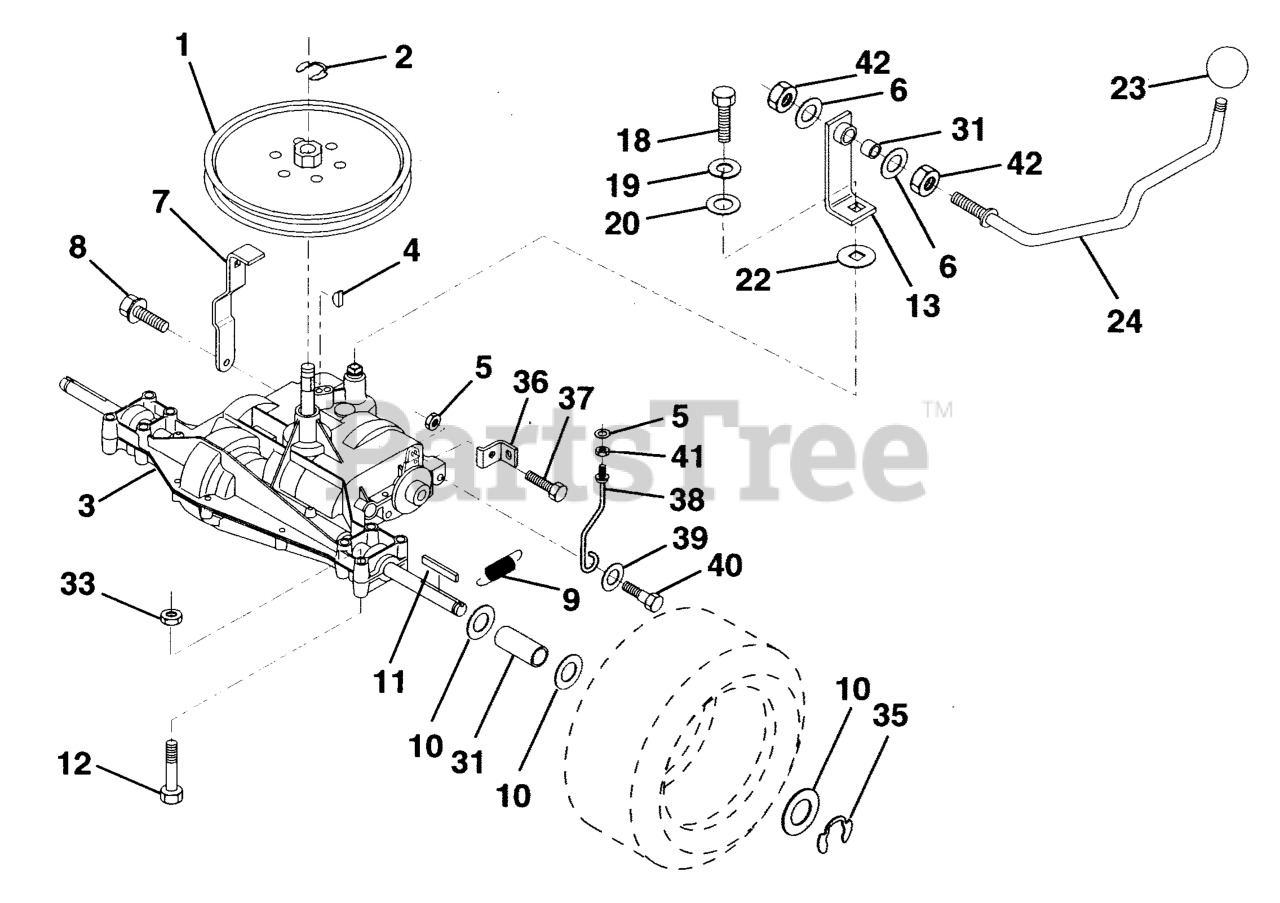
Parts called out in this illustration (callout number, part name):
2	RETAINING RING LT
4	KEY STD (1373) DANA
5	LOCKNUT
7	STRAP TORQUE
8	SCREW.THDROL.5/16-18X3/4.TTY
9	SPRING T
11	SQUARE KEY
12	Bolt Fin Hex 3/8 - 16 x 2 3/4
13	BRACKET NLA
18	Bolt, Hex Head, Fin. l/4-28 UNF x 3/4 Grade 8
19	LOCKWASHER
20	WASHER LT
22	WASH-SHFT PLT LT
23	KNOB T (1/2-HOLE)
36	Bracket Brake
37	RP BOLT 5/16-18 X3/4 ZN/YEL GR
38	BELT KEEPER RH
39	WASHER GT
40	Bolt, Shoulder 5/26 - 18
41	BOLT SHD 5/16-18
42	Nut, Centerlock
